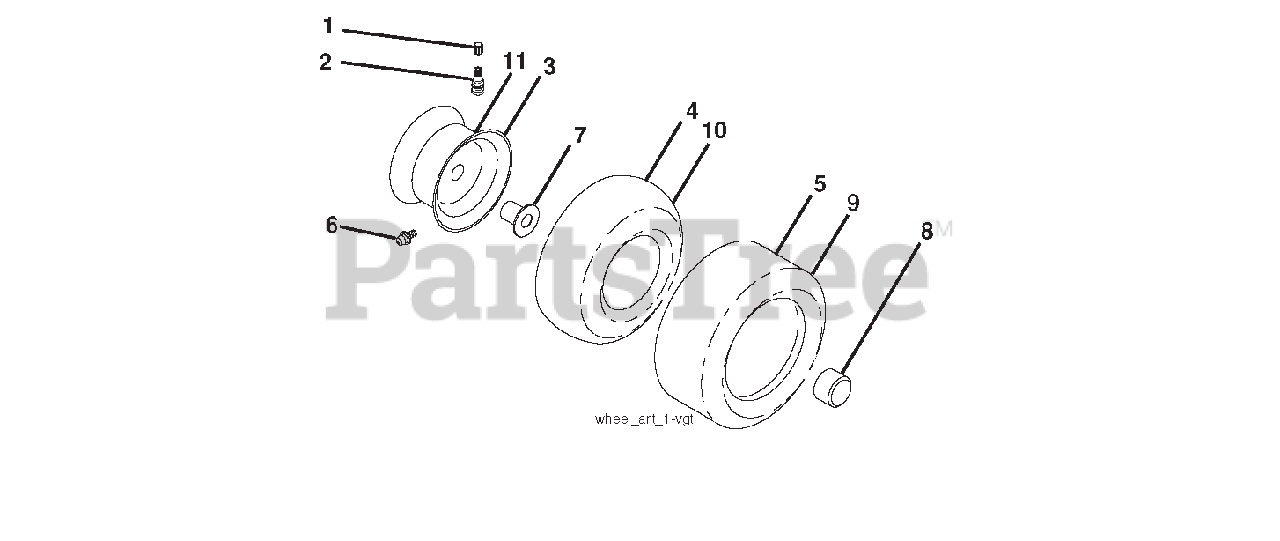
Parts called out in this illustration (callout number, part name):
1	CAP.VALVE.TIRE
2	STEM.VALVE
3	RIM ASSEMBLY 6" FRONT
4	TUBE.INNER.FRONT.#35060
5	TIRE.F.TS.15 X 6.0 - 6.SERVICE
6	FITTING, GREASE
7	BEARING FLANGE
8	CAP AXLE (FRONT WHEEL ONLY)
9	TIRE.R.TS.20 X 8-8.C.SERVICE
10	TUBE, REAR
11	RIM ASSEMBLY 8" REAR
